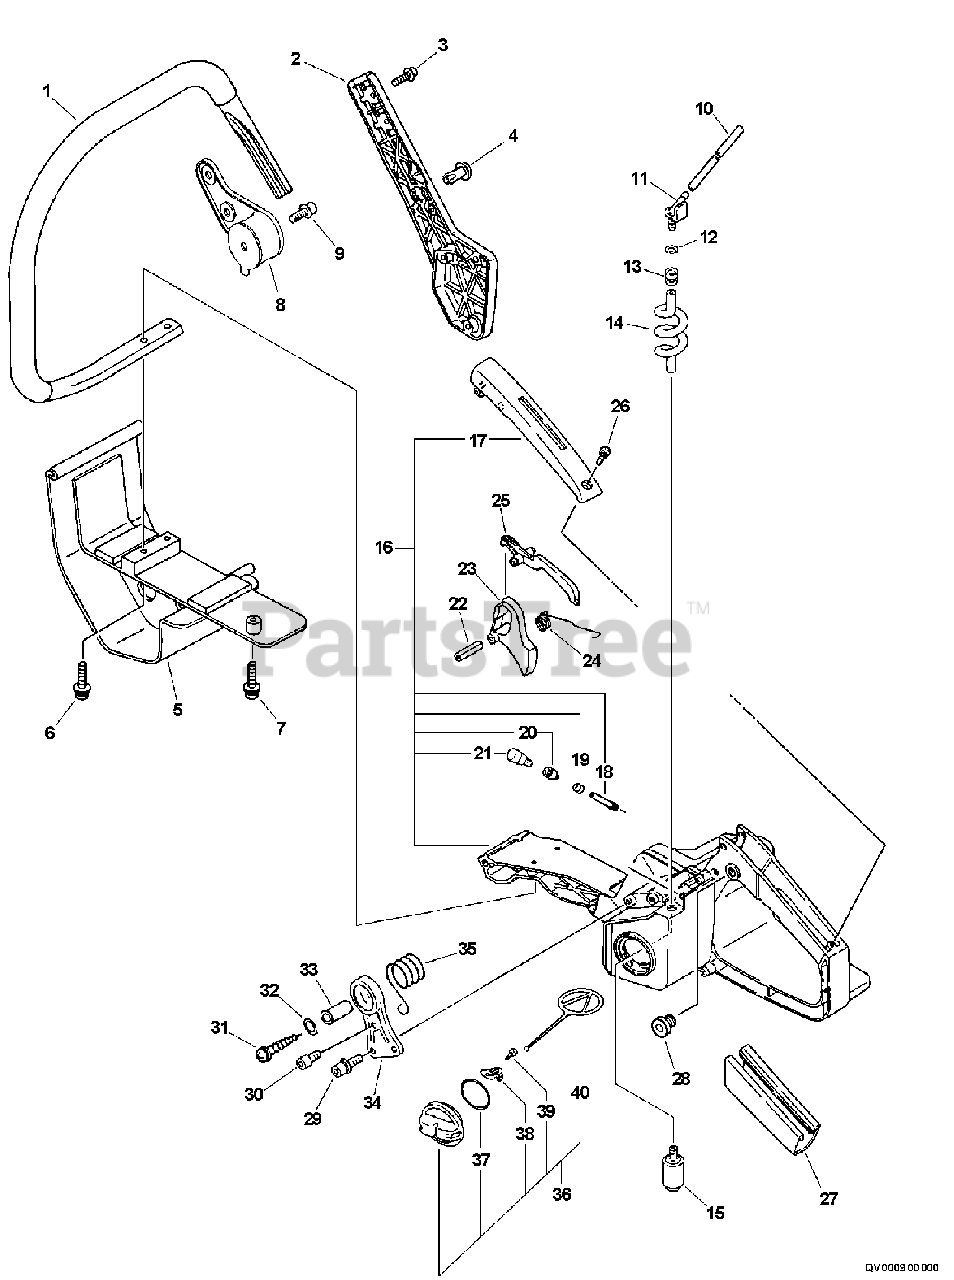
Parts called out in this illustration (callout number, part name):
1	HANDLE, FRONT
2	BRACKET, GRAY HANDLE
3	SCREW 5×20
6	BOLT 5×30
7	BOLT 5×25
8	CUSHION 5
9	BOLT 5×14
10	PIPE, FUEL 3×6×110
11	CONNECTOR, PIPE
12	CLIP Ø6.5 MM
13	GROMMET
14	PIPE, FUEL
15	FILTER, FUEL
16	REAR HANDLE ASSY
17	COVER, HANDLE
18	PIPE, VENT
20	HOLDER, VENT
21	VENT ASSY
22	PIN, SPRING Ø5×25 MM
23	TRIGGER, THROTTLE
24	SPRING, THROTTLE RETURN
25	LEVER, THROTTLE LOCKOUT
26	SCREW 4×14
27	GRIP, HANDLE
29	BOLT 5×14
30	BOLT 5×8
31	SCREW - 5×35
32	WASHER 5
33	COLLAR 5
34	BRACKET, CUSHION
35	SPRING, COMPRESSION
36	CAP ASSY, FUEL
37	O-RING 29
38	RETAINER, CONNECTOR
39	SCREW, TAPPING 3×8
40	CONNECTOR, CAP L= 60 MM
